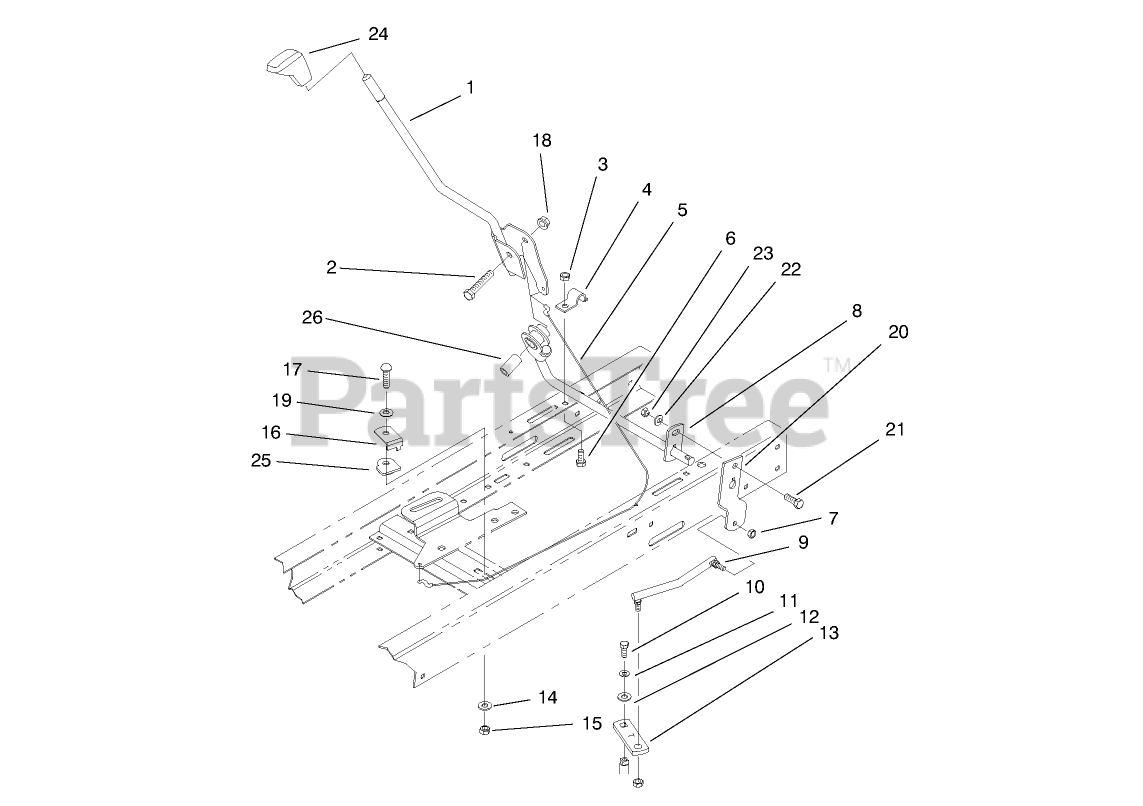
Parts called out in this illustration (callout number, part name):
1	LEVER-SHIFT ASM
2	SCREW-HH
3	NUT-LOCK, NI
4	CLAMP-PIVOT, SHIFT
5	CABLE-CLUTCH
6	SCREW-HH
7	NUT-LOCK
8	SHIFT PIVOT ASM
9	LINK-SHIFT
10	SCREW-HH
11	WASHER-LOCK
12	SPACER
13	LEVER-SHIFT
14	WASHER-PLAIN
15	NUT-LOCK, NI
16	KEEPER-CABLE
17	SCREW-CARR
18	NUT-LOCK, NI
19	WASHER-FLAT
20	LEVER-PIVOT, SHIFT
21	SCREW-HH
22	WASHER-PLAIN
23	NUT-LOCK, NI
24	KNOB-SHIFT
25	GUIDE-CABLE
26	BUSHING-SHIFT, LEVER
